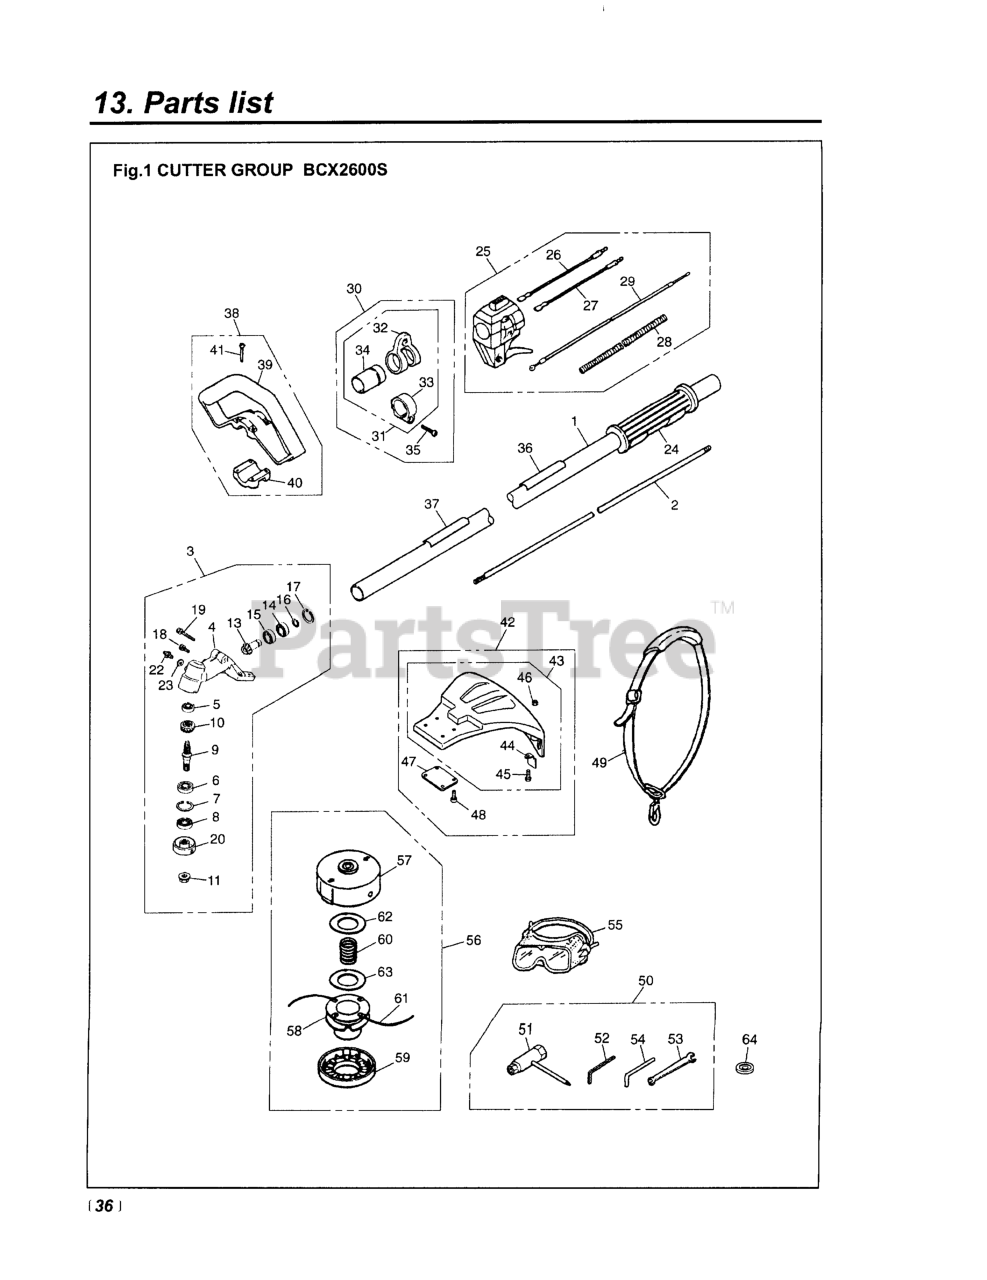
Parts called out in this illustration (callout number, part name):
3	GEARCASE ASSY (RPLS -13000)
4	GEARCASE
5	BEARING (RPLS T3300-13521)
6	BEARING (RPLS T3403-13510)
7	RING, SNAP, M26 X 1.2
8	SEAL, OIL
9	SHAFT
10	GEAR
11	NUT
13	PINION
14	BEARING (RPLS T3300-13531)
15	BEARING (RPLS T3403-13530)
16	RING, SNAP (RPLS T3300-13330)
17	RING, SNAP, M24 x 1.2
18	BOLT, M5 X 10
19	BOLT
20	HOLDER (A)
22	FITTING, GREASE
23	WASHER, M6 X .8
24	GRIP (RPLS 3577-32140 & 3220-
25	LEVER FOR BCX
26	CORD (A), BLACK
27	CORD (B), RED
28	TUBE (RPLS 4900-72141)
29	CABLE (RPLS 5580-83100)
30	HANGER ASSEMBLY
31	HANGER COMPLETE
32	HANGER
33	CLAMP
34	SLEEVE
36	PLATE, NAME (BCX2600DL)
37	PLATE, CAUTION
38	HANDLE ASSEMBLY
39	HANDLE
42	GUARD ASSY (RPLS -24000)
43	GUARD COMP (RPLS. -24100)
44	BLADE (RPLS T3002-24120)
46	NUT
47	PLATE
48	BOLT (USE 3310-31720)
51	SOCKET
52	WRENCH (TOOL)
53	SPANNER, 8 X 10 (RPLS 2540- )
54	BAR
55	GOGGLE
56	4
57	CASE (RPLS -15112)
58	HOLDER, CORD (RPLS -15141)
59	COVER (RPLS -15130)
60	SPRING (RPLS -99161)
61	CORD
62	PLATE, LARGE
63	PLATE, SMALL
64	HOLDER (B)
